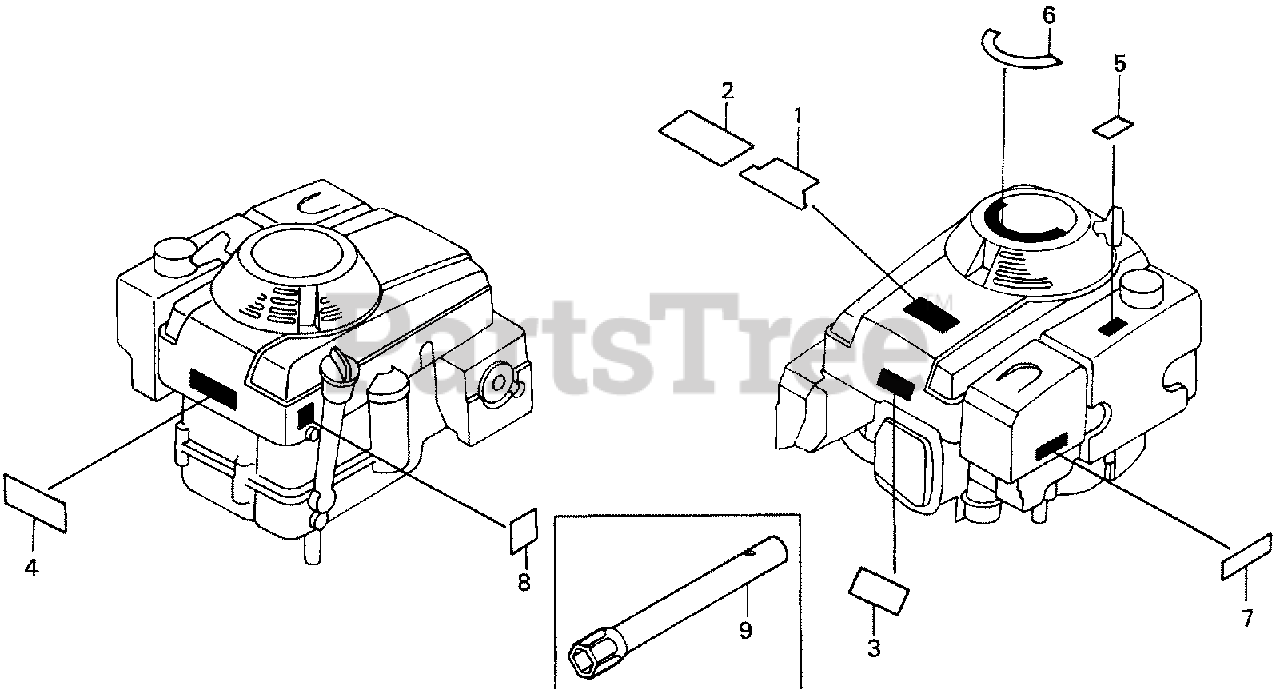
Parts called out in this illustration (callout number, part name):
2	EMBLEM, TOP COVER (E)
4	MARK, CAUTION
6	MARK, EASY START (ENGLISH)
7	MARK, AIR CLEANER CAUTION
8	MARK, OIL CAUTION
9	WRENCH, BOX (P21)
